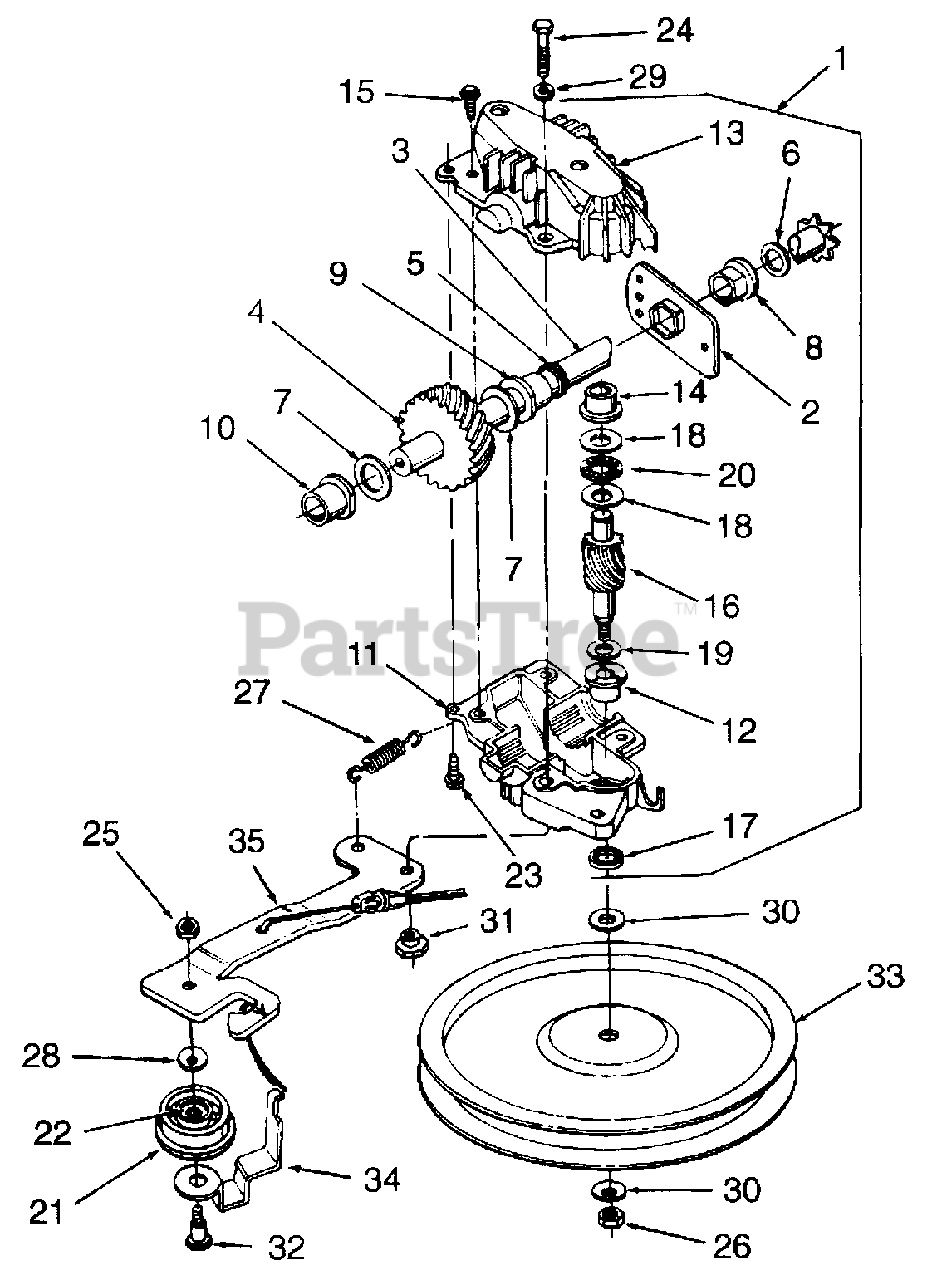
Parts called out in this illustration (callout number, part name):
1	Transmission Assembly, Complete
3	Shaft, Output w/6T Sprocket
4	Gear, Helical 34T
5	Seal, Oil, .625 x .812
6	Washer, Flat, .64 x 1.24 x .06 HD
7	Washer, Flat, 5/8 x 1.0
8	Bearing, Hex Flange, .631 ID
9	Bearing, Flange, .629 ID
10	Bearing, Flange, .566 ID
11	Housing, Lower
12	Bearing, Flange, .503 ID
13	Housing, Upper
14	Bearing, Flange, .378 ID
15	Screw, Hex Tapp, #10-16 x .75
16	Shaft, Pinion 10T
17	Seal, Oil, .50 x .687
18	Washer, Thrust, .382 x .684
19	Washer, Flat, .504 x .70 x .030
20	Bearing, Thrust, .375 x .812
21	Pulley Ass'y, Idler w/Bearing
22	Bearing, Needle, .375 x .375
23	Screw, Hex Tapp, #10-16 x .75
24	Screw, Hex w/Patch, 1/4-20 x 1.25
25	Nut, Hex, 1/4-28
26	Nut, Hex Jam, 5/16-24 L.H. Thd
27	Spring, Extension, 1.12 Lg
28	Washer, Bell, .265 x .75 x .06
29	Washer, Lock, 1/4
30	Washer, Bell, .325 x .930 x .045
31	Shoulder Spacer, .375 x .165
32	Shoulder Bolt, 1/4-28 x .375
33	Pulley, Flat, 5.06 Dia
34	Belt Keeper
35	Bracket, Idler
